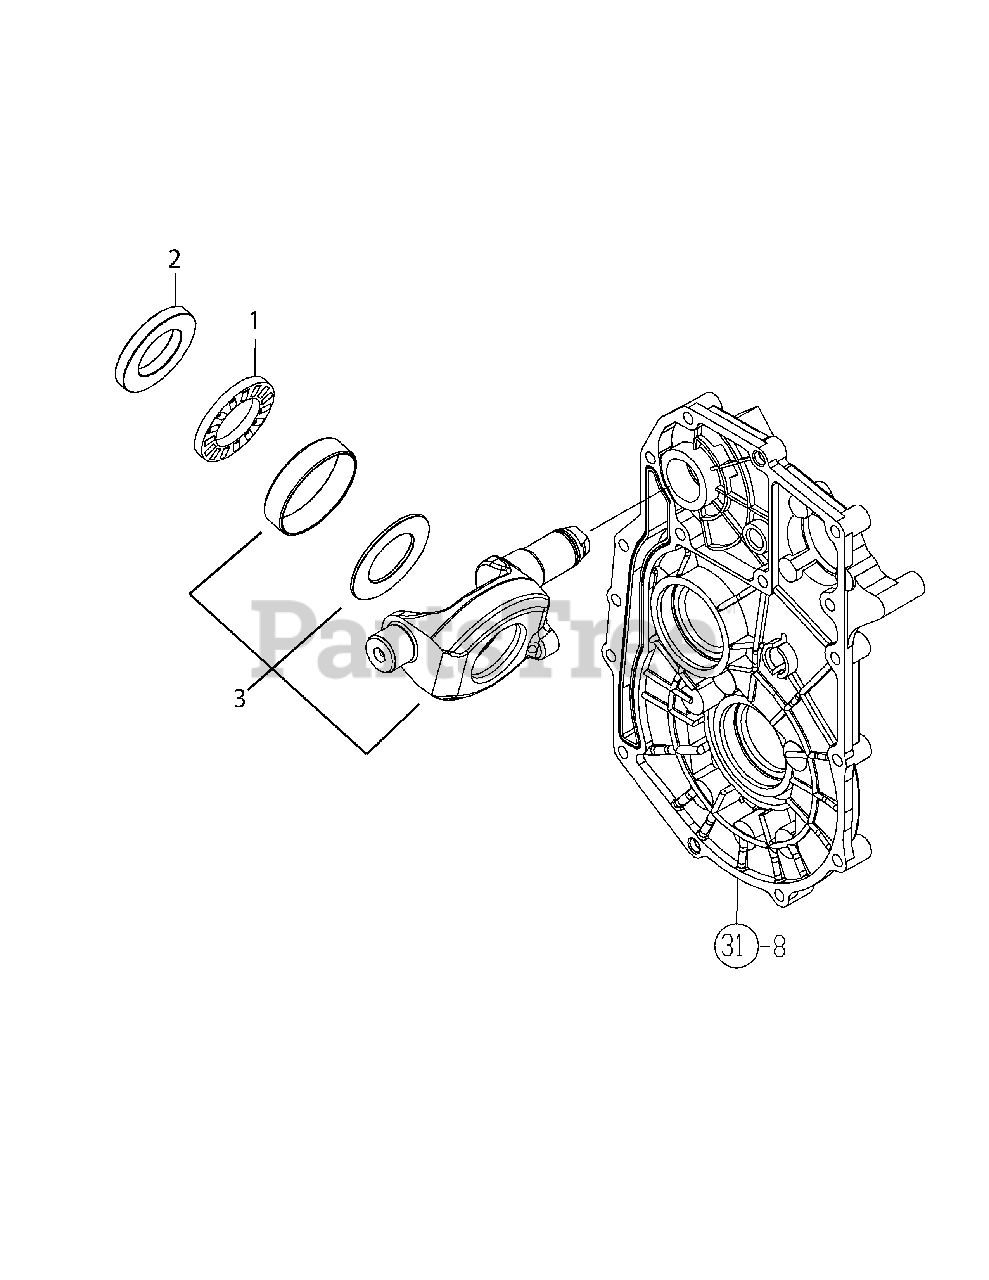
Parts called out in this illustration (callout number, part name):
1	BEARING, THRUST
2	PLATE, THRUST A
3	SHIFT ASSEMBLY
